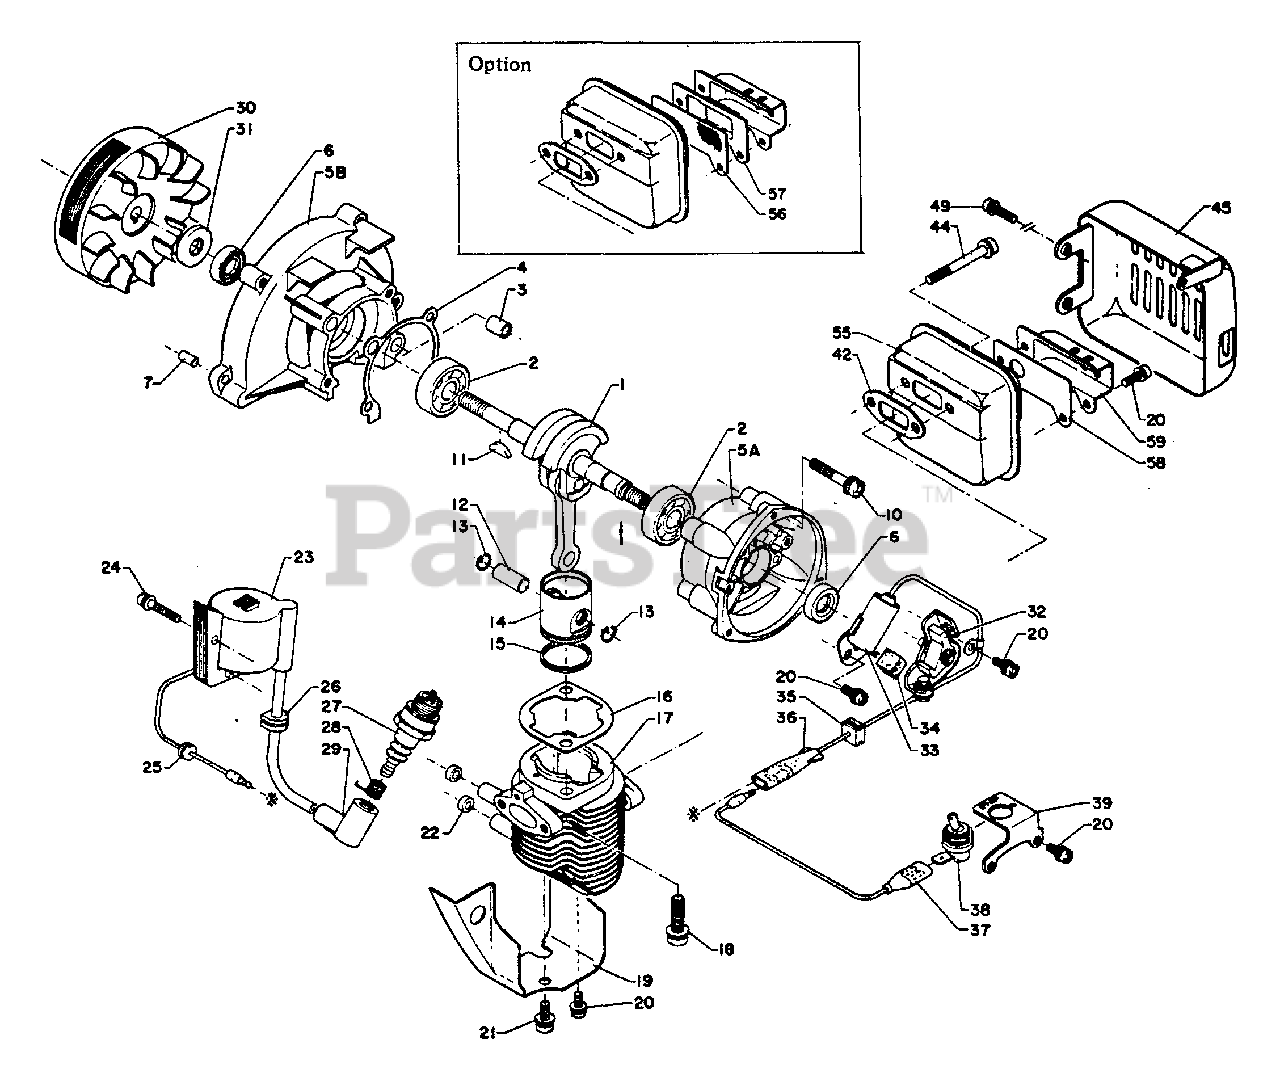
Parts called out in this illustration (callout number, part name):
1	CRANKSHAFT ASSY
2	BEARING, BALL - 6200
3	PIN - LOCATING
4	GASKET, CRANKCASE
5	CRANKCASE KIT
5A	CRANKCASE KIT
5B	CRANKCASE KIT
6	SEAL, OIL
7	PIN - LOCATING
10	SCREW - 5X30
12	PIN, PISTON
13	RING, RETAINING
14	PISTON
15	RING, PISTON
16	GASKET, CYLINDER
17	CYLINDER
18	SCREW - 6X22
19	COVER, ENGINE
20	SCREW - 4X10
21	SCREW - 5X10
22	SPACER
23	COIL, IGNITION
24	SCREW - 4X22
25	GROMMET
26	GROMMET
27	SPARK PLUG -- BM-6A
28	TERMINAL, SPARK PLUG CAP
29	CAP, SPARK PLUG
30	FLYWHEEL
32	CONTACT POINT SET
33	CONDENSER
34	PAD, OIL
35	GROMMET
36	CORD, PRIMARY
37	LEAD - GROUND
38	SWITCH, IGNITION
39	BRACKET, SWITCH
42	GASKET, EXHAUST
44	SCREW - 5X40
45	COVER, MUFFLER
49	SCREW - 4X14
55	CASE, MUFFLER
56	SCREEN, SPARK ARRESTOR
57	RETAINER, SCREEN
58	GUIDE, EXHAUST - INNER
59	GUIDE, EXHAUST
